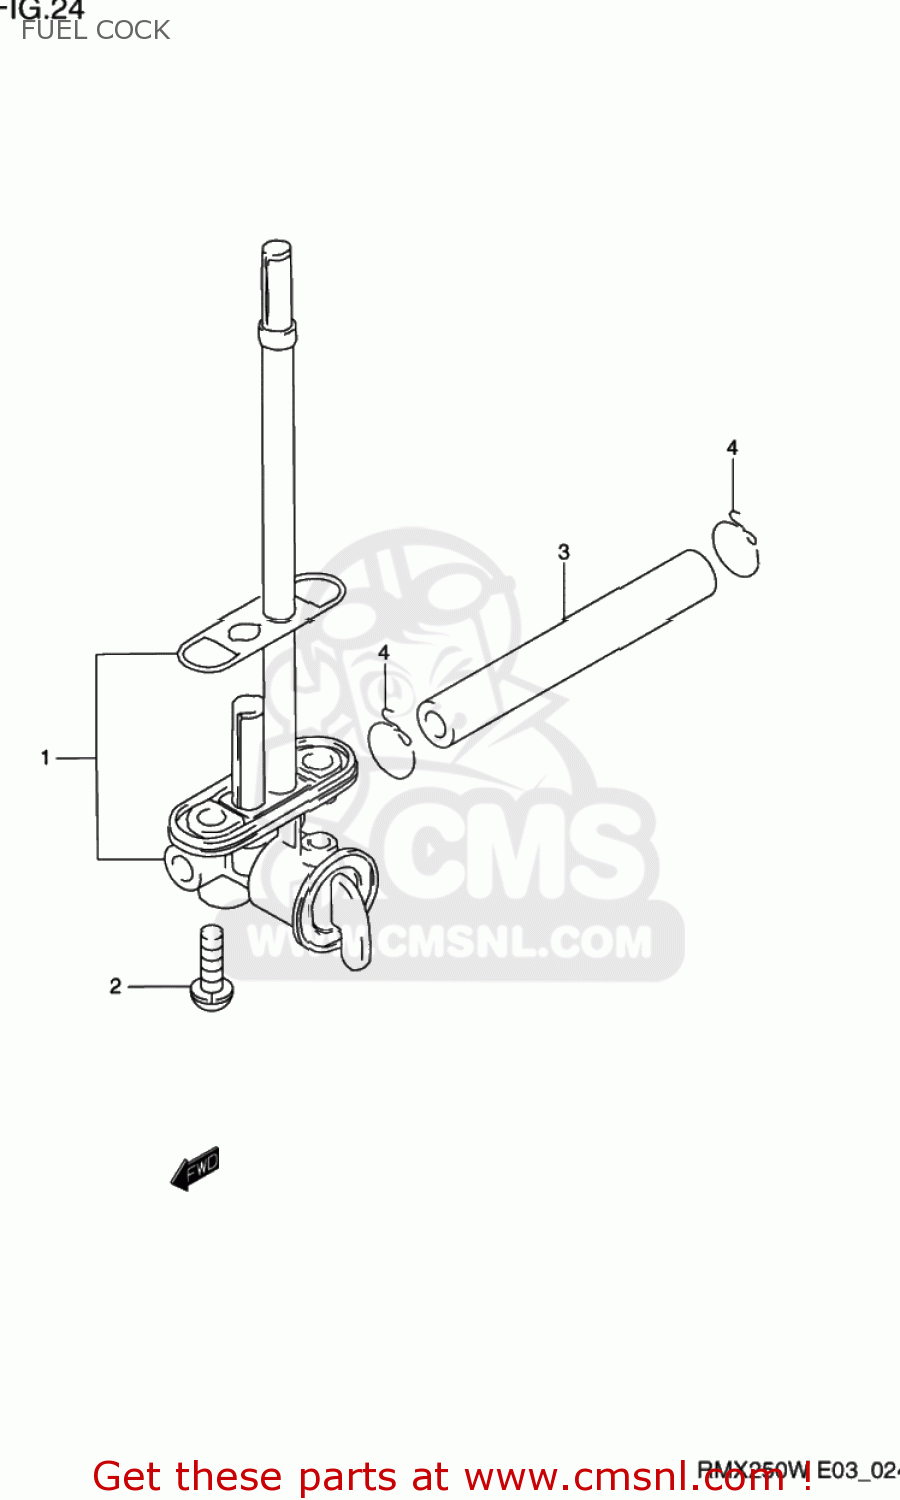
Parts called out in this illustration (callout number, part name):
1	COCK ASSY,FUEL
2	SCREW
3	HOSE,FUEL
4	CLIP
